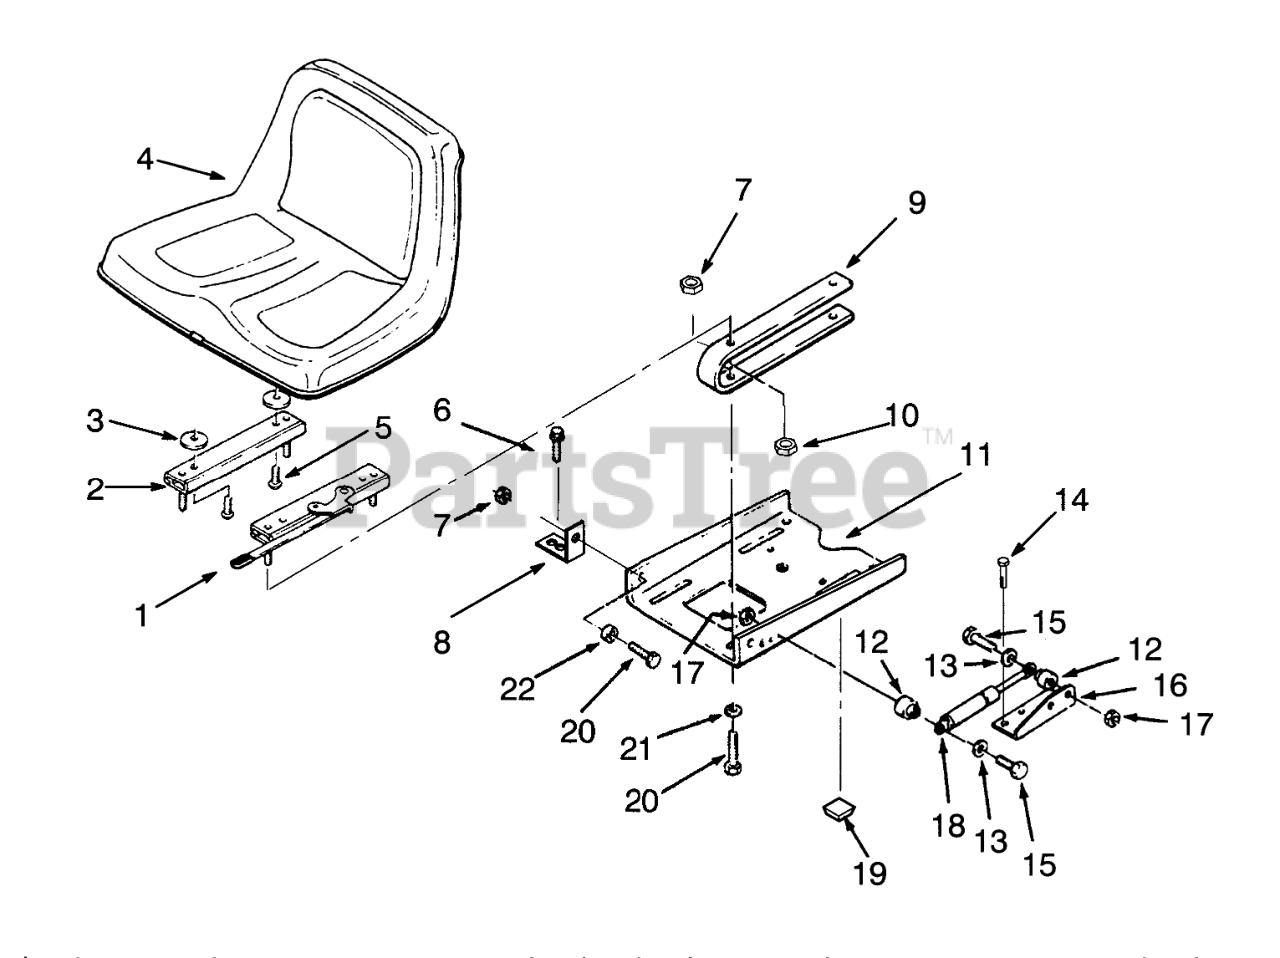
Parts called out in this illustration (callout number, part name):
1	Adjuster-Seat
2	ADJUSTER-R.H. SEAT
3	SPACER-NYLON
4	Seat
6	Bolt
7	NUT-LOCK, NI
8	BRACKET-PIVOT
9	Seat Spring
10	Nut
11	Plate-SeatPivot
12	SPACER
13	WASHER-FLAT
14	Bolt
15	SCREW-HH
16	BRACKET-CYLINDER R
17	NUT-LOCK, NI
18	GAS SPRING
19	BUMPER SJ5514 BLACK
20	SCREW-HH
21	WASHER-PLAIN
22	BUSHING
